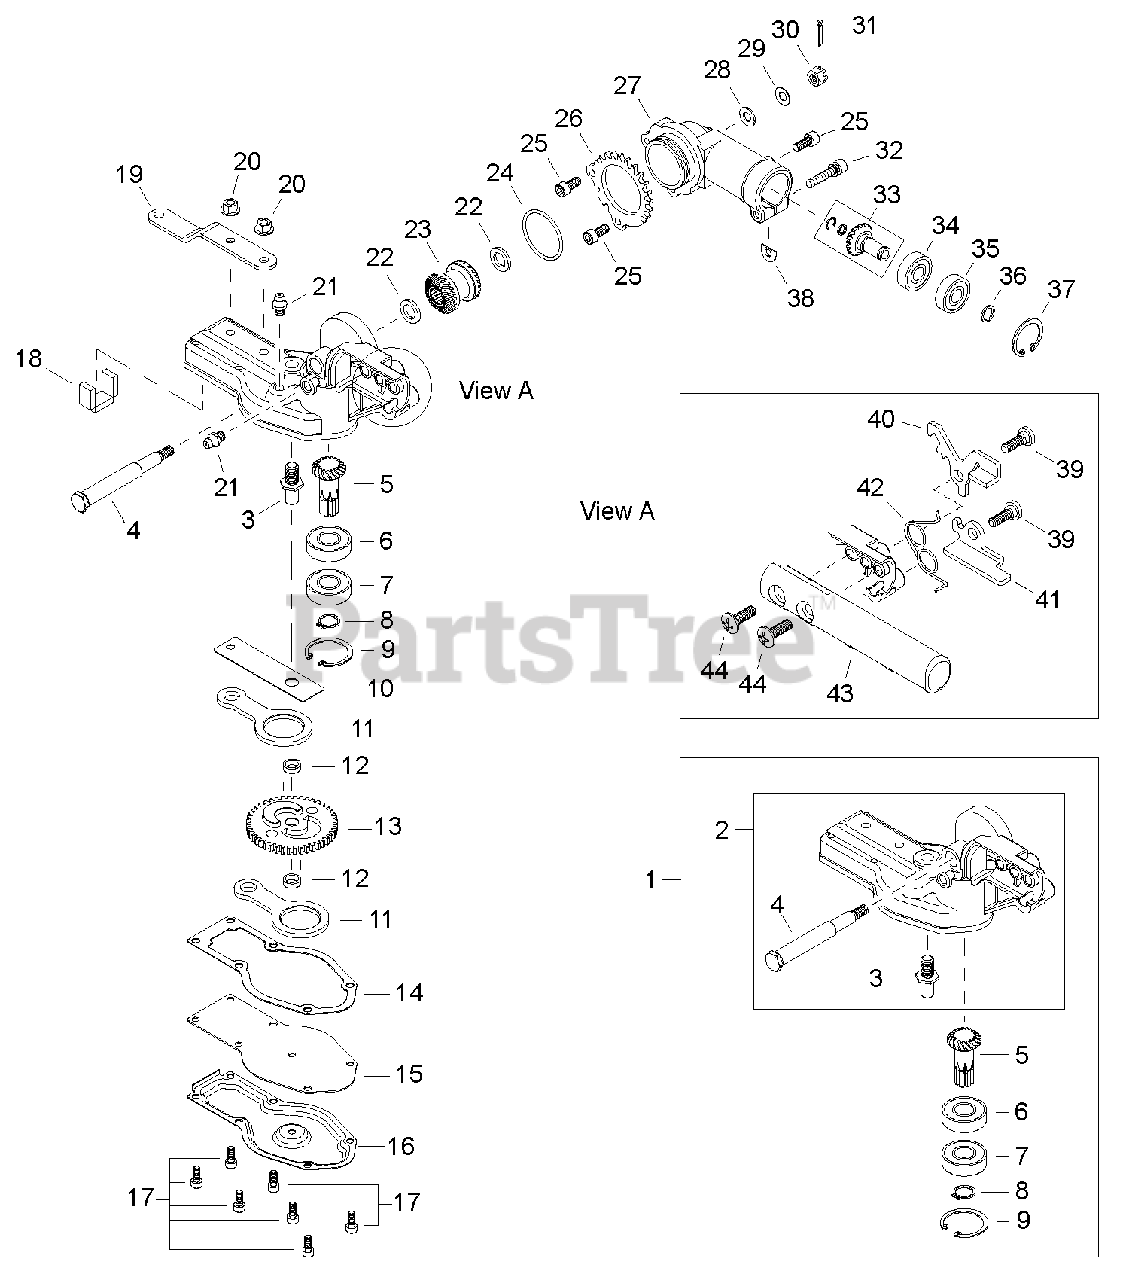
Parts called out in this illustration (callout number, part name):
2	GEAR CASE HOUSING ASSY
3	MAINSHAFT
4	SHAFT
5	SHAFT, PINION
6	BEARING, BALL 6001
7	BEARING, BALL 6001ZZ
8	RING, SNAP Ø12
9	RING, SNAP Ø28
10	PLATE, GUIDE
10-1	GEAR CASE HOUSING KIT
11	CONROD
12	SPACER Ø11ר8×3.4
13	GEAR, CAM
14	GASKET, GEAR CASE
15	SPACER
16	COVER, GEAR CASE
17	BOLT 4×10
18	PACKING, FELT
19	BRACKET, CUTTER
20	NUT, FLANGE M5
21	FITTING, GREASE
22	COLLAR Ø16ר10×L= 2
23	GEAR, BEVEL
24	O-RING
25	BOLT 5×12
26	RING, LOCKING
27	HOUSING, UPPER GEAR CASE
28	WASHER 6.5×13×1
29	WASHER, CONE M6
30	NUT M6
31	PIN, COTTER Ø1.6×15
32	BOLT M5×25
33	PINION SET, BEVEL
34	BEARING, BALL 609
35	BEARING, BALL 609ZZ
36	RING, SNAP
37	RING, SNAP Ø24
38	D-WASHER
39	BOLT M6
40	LEVER, LOCK
41	RELEASE, LOCK
42	SPRING, TORSION
43	LEVER, ADJUSTMENT
44	SCREW, TRUSS M6×20
